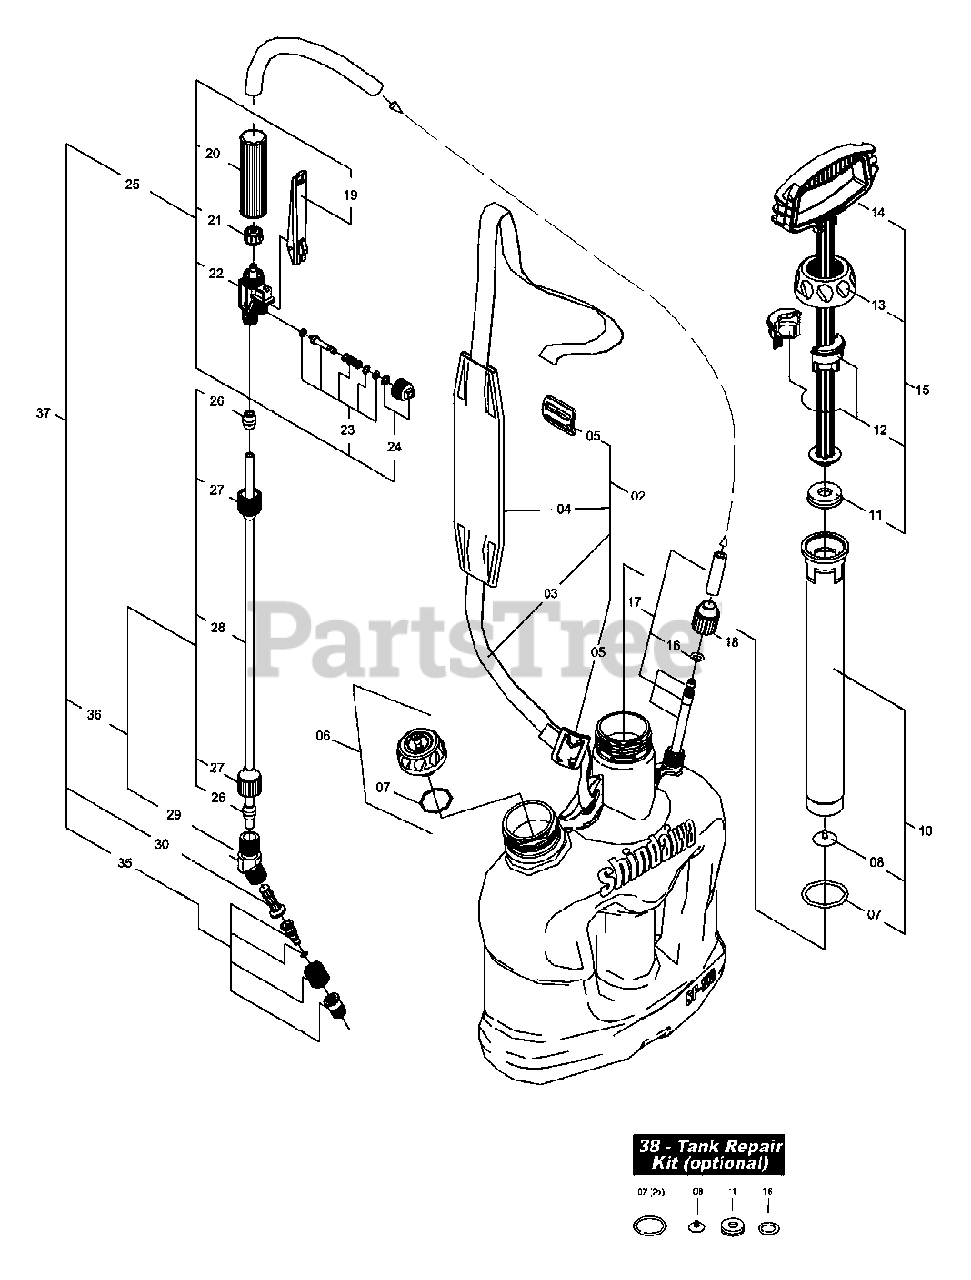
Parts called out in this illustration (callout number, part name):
02	STRAP ASSY
03	STRAP 1800MM
04	PAD, SHOULDER
05	BUCKLE, STRAP - LOWER
06	TANK LID ASSY
07	O-RING, TANK LID
08	DIAPHRAGM VALVE, VITON(R)
10	PUMP TUBE ASSY
11	CUP, PISTON
12	BUSHING
13	CYLINDER CAP
14	LABEL - GENERATOR
15	PUMP HANDLE ASSY
16	O-RING - 110
17	DIP TUBE WITH HOSE
18	NUT - 20X1.5
19	TRIGGER
20	HANDLE, TRIGGER VALVE
22	BODY, TRIGGER VALVE
23	TRIGGER VALVE NEEDLE ASSY
24	TRIGGER VALVE CAP ASSY
25	TRIGGER VALVE ASSY
26	CONE PACKING
27	SCREW
28	SPRAY WAND TUBE
29	ELBOW
30	NOZZLE FILTER
35	ADJUSTABLE CONE NOZZLE
36	SPRAY TUBE ASSY
37	SPRAY WAND ASSY
38	SEAL KIT
